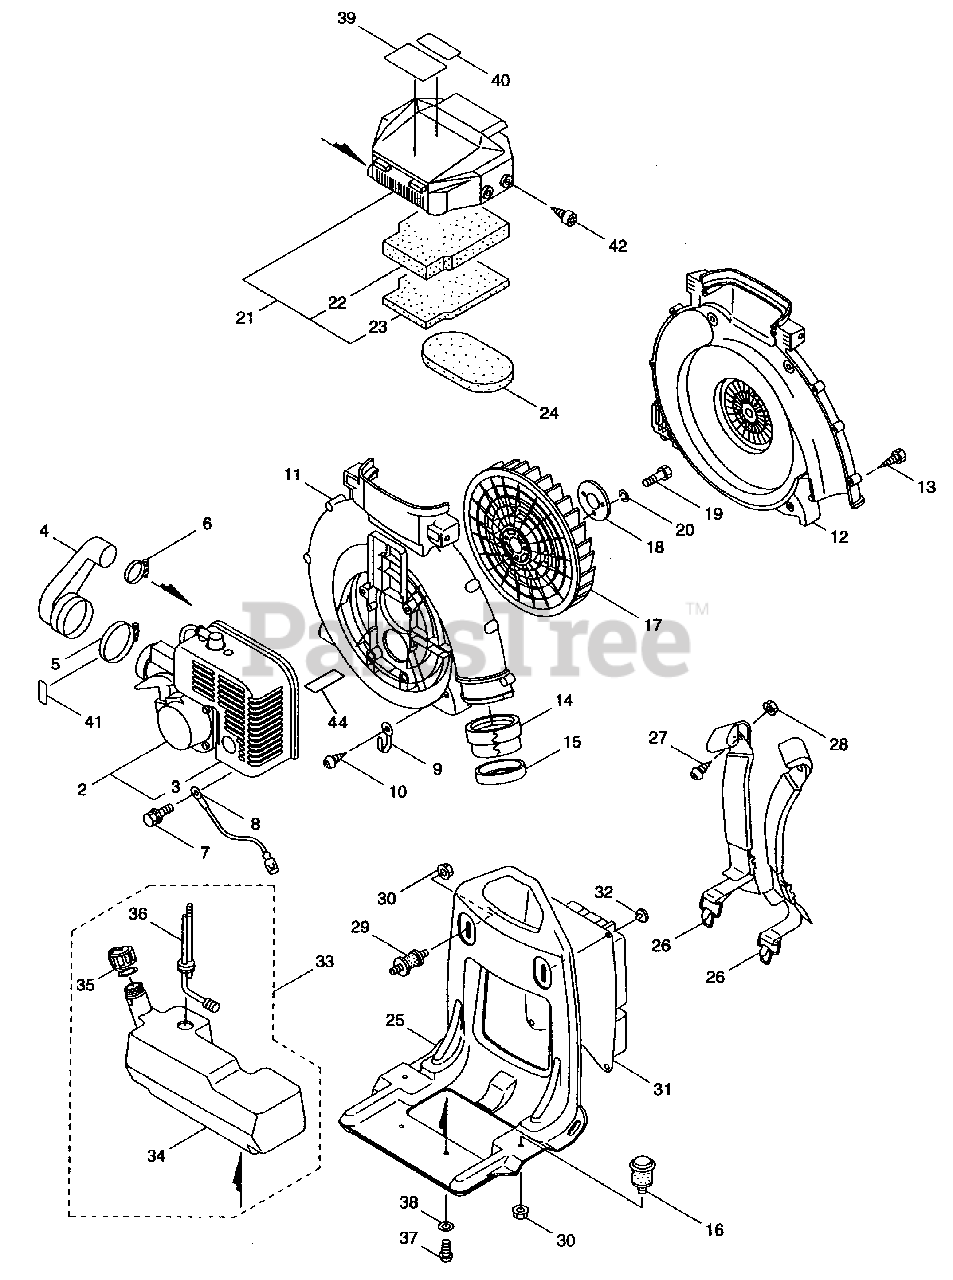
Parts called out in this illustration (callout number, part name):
1	Blower Assembly
2	Engine (Incl. Ref. # 3)
4	Pipe-Inlet
8	Cord-Earth
10	Screw-Tapping
11	Case-Fan (E)
12	Case-Fan (S)
13	Screw-Tapping
15	Rubber Band
20	Washer-Spring
21	Air Cleaner Assembly (Incl. Ref. # 22,23)
22	Element
25	Frame-Knapsack
26	Band-Knapsack
27	Screw
31	Cushion Pad
33	Fuel Tank Assembly
34	Tank-Fuel
35	Cap Assembly
36	Filter Assembly
41	Decal-Choke
42	Screw-Tapping
43	Decal-Hot Surface
